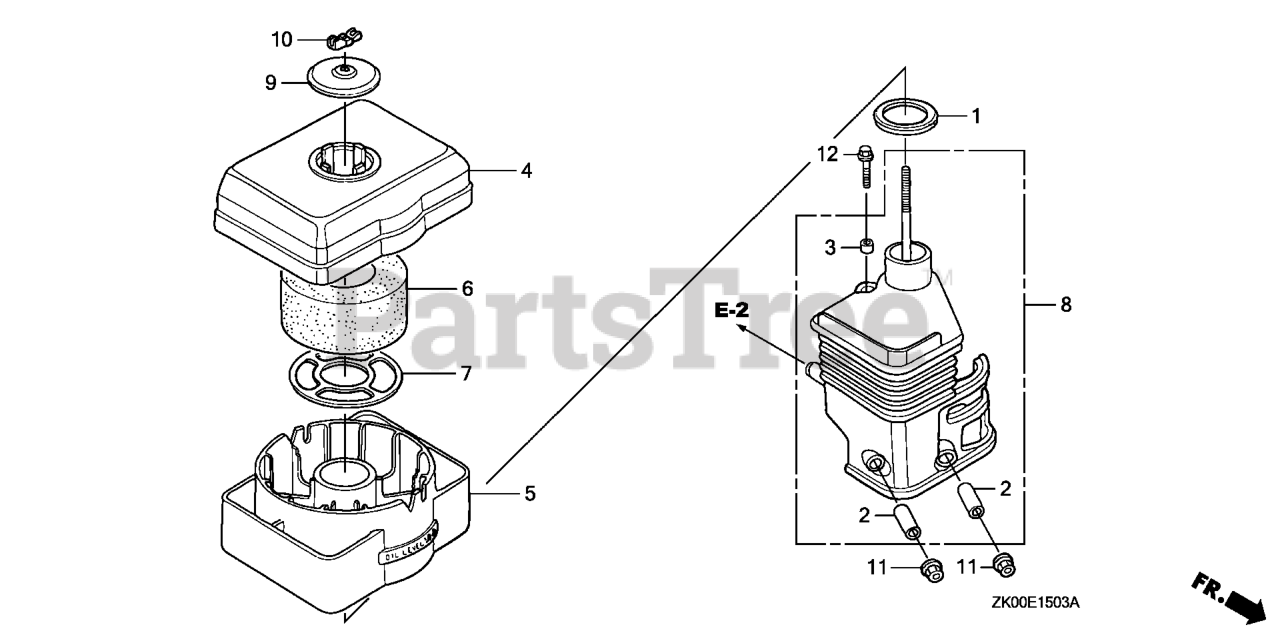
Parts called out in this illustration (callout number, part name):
1	GASKET, ELBOW
2	COLLAR, AIR CLEANER Use from Engine SN 1786085.
3	COLLAR B, AIR CLEANER
4	BODY, CLEANER (OIL BATH)
5	PAN, CLEANER OIL (OIL BATH)
6	ELEMENT, AIR CLEANER (OIL BATH)
7	GRID, AIR CLEANER
8	ELBOW, AIR CLEANER
9	CAP, CLEANER
10	WINGNUT, TOOL BOX SETTING
11	NUT, FLANGE (6MM)
12	BOLT, FLANGE (6X20)
